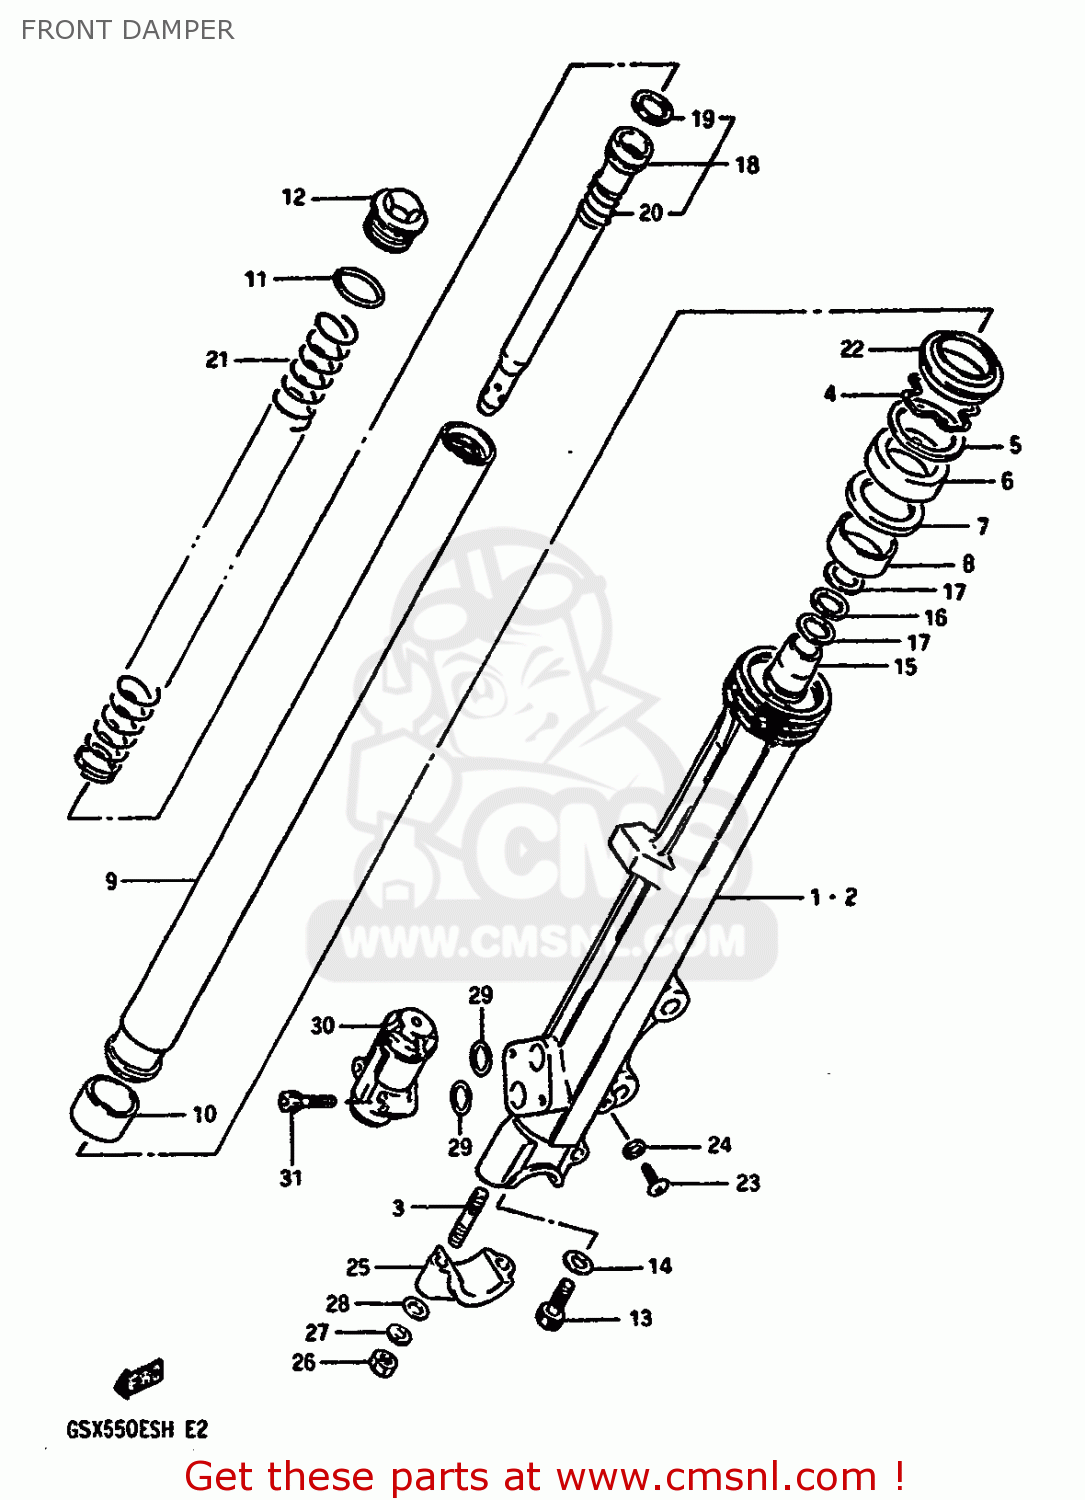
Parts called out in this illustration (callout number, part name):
1	TUBE,FORK,OUTER,RIGHT
2	TUBE,FORK,LEFT,OUTER
3	STUD 8X30
4	RING,STOPPER
5	WASHER. FRONT FORK
6	OIL SEAL,FRONT FORK
7	WASHER
8	METAL,SLIDE
9	TUBE,FORK INNER
10	METAL,FR FORK PISTON
11	O RING
12	CAP
13	BOLT,FORK CYLINDER(10X25)
14	GASKET (NAS)
15	PIECE,OIL LOCK
16	WASHER
17	SPRING,LEAF
18	CYLINDER,FRONT FORK
19	RING,PISTON
20	SPRING,REBOUND
21	SPRING
22	SEAL,DUST
23	SCREW
24	GASKET,DRAIN,PLUG (NAS)
25	HOLDER,AXLE
26	NUT
27	WASHER,LOCK,8.
28	WASHER
29	O RING
30	PDF ASSEMBLY
31	BOLT
